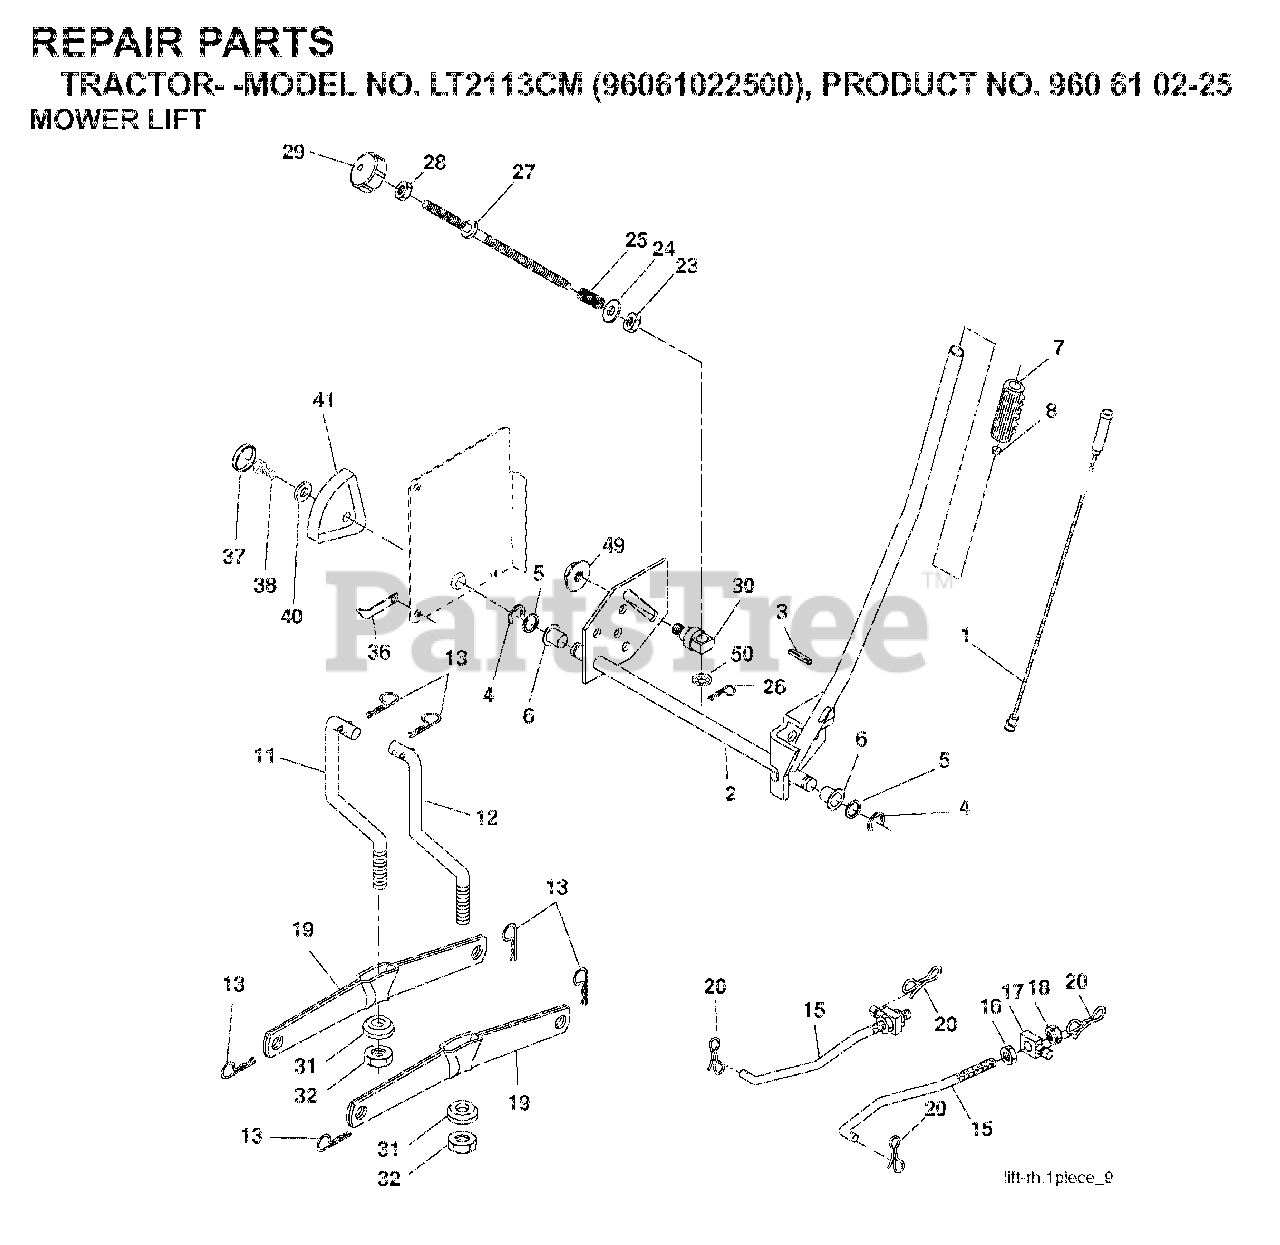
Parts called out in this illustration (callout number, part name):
4	RETAINING RING LT
6	BEARING.NYLON
7	GRIP
8	PLUNGER BUT KIT
11	LINK
12	LINK
13	RETAINER-SPRNG RB
15	LINK.SUSPENSION.FRONT
16	NUT
18	NUT
19	ARM.REAR.SUSPENSION
20	PIN.COTTER.7/16.BOW TI
25	SPRING**
26	RETAINER CLIP
27	ROD ADJ LIFT
28	NUT
29	KNOB INF 3/8-16
31	BEARING.PIVOT.LIFT
32	NUT CROWNLOCK 3/8-24
36	POINTER, HEIGHT INDICATOR
37	PLUG,HOLE
38	SCREW 5/16-18X1
41	HEIGHT INDICATOR
49	NUT
50	NUT PUSH M
